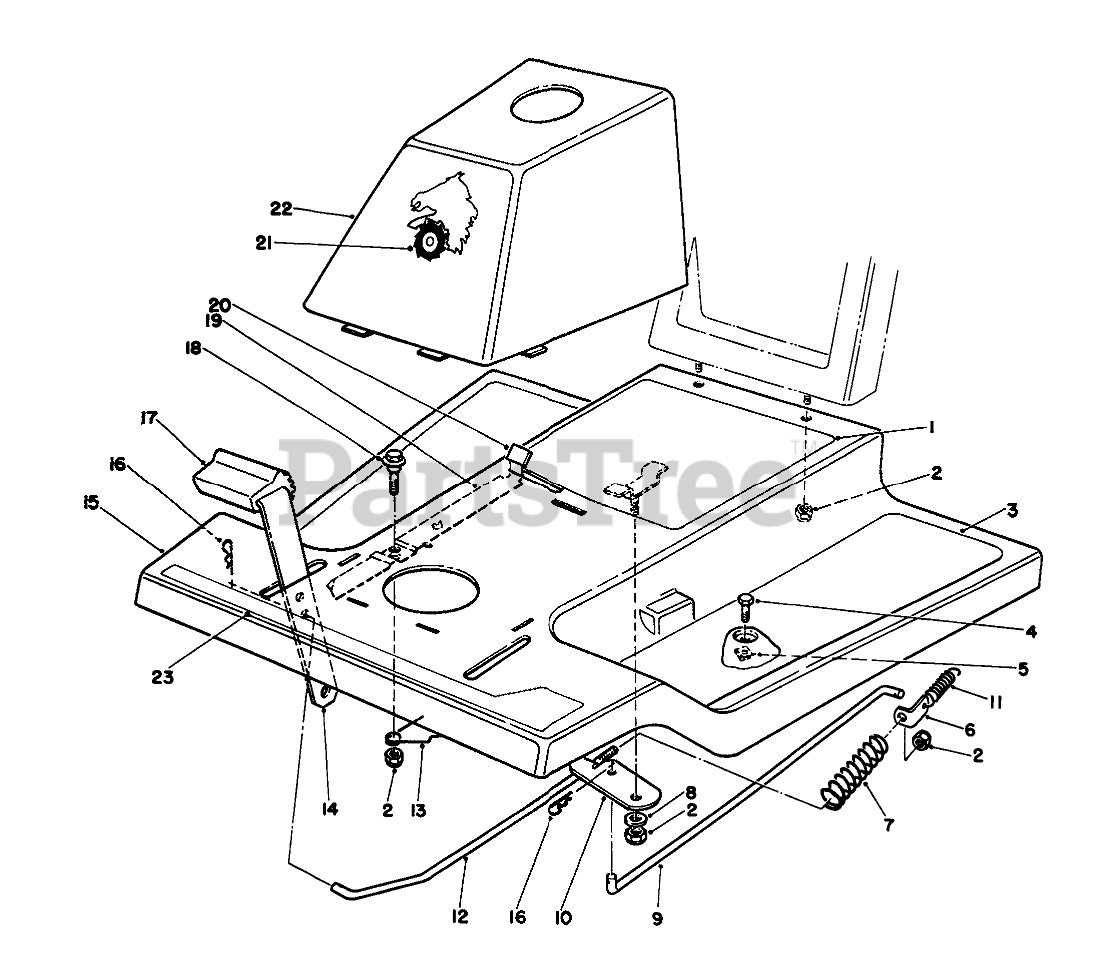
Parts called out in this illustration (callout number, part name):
1	DECAL - INSTRUCTION
2	NUT-LOCK, NI
3	TREAD-FOOT
4	SCREW-HH
5	NUT-TINNERMAN
6	BRACKET-BRAKE RETURN
7	SPRING-TRACTION BRAKE
8	WASHER-PIVOT
9	ROD-TRANS BRAKE
10	Lever-Brake, Bellcrank
11	SPRING-IDLER
12	ROD-FRONT BRAKE
13	SPRING-PARKING BRAKE
14	Pedal-Brake & Clutch
15	Body W.A.-Front
16	PIN-COTTER
17	PAD-PEDAL
18	SCREW-SHOULDER
19	Parking Brake
20	TIP-PARKING BRAKE
21	DECAL - HORSEHEAD
22	Tower (Incl. Ref. #21)
23	85-AL - RECYCLER
